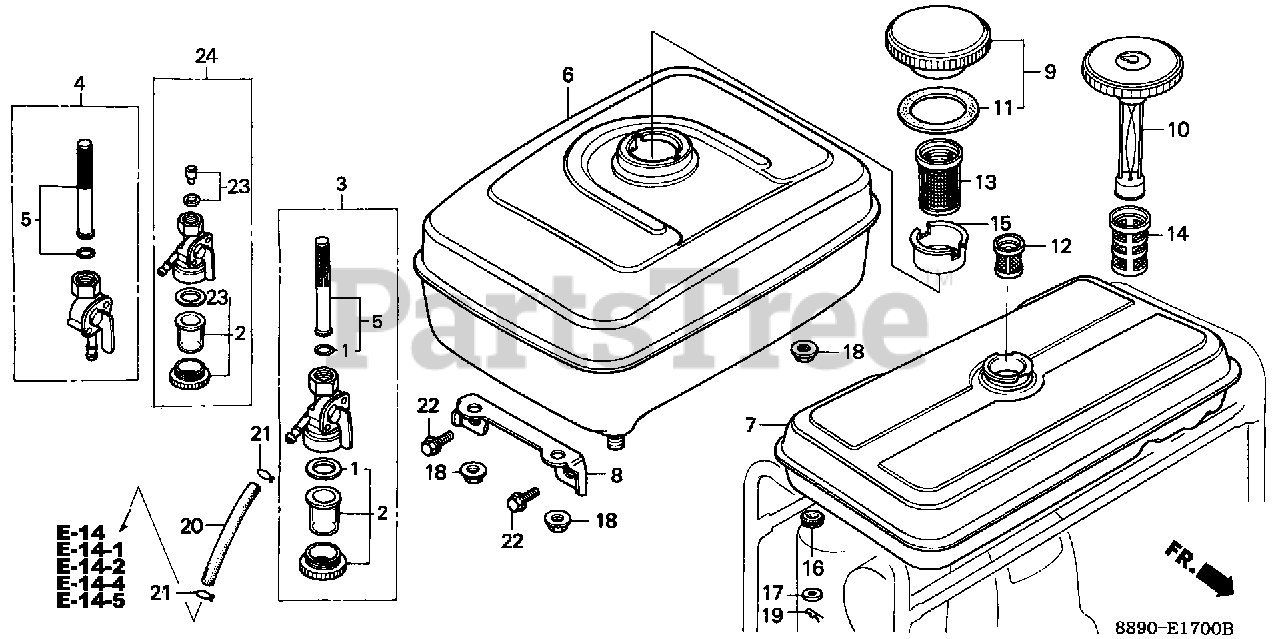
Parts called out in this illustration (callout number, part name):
1	GASKET SET, PETCOCK
2	CUP, FUEL STRAINER
2	CUP SET, FUEL STRAINER
3	PETCOCK ASSY.
4	PETCOCK ASSY.
4	PETCOCK ASSY. (NOT AVAILABLE)
5	SCREEN SET
6	TANK, FUEL *NH31* (MCKINLEY WHITE)
6	TANK, FUEL (LONG TAIL) (NOT AVAILABLE)
6	TANK, FUEL *NH31* (MCKINLEY WHITE) (NOT AVAILABLE)
8	STAY, FUEL TANK (NOT AVAILABLE)
9	CAP, FUEL FILLER (BLACK)
9	CAP, FUEL FILLER
10	GAUGE, FUEL (ENGLISH)
11	GASKET, FUEL FILLER CAP (39X58X3)
13	FILTER, FUEL
15	HOLDER, FUEL FILTER
18	NUT, FLANGE (8MM)
20	BULK HOSE, FUEL (4.5X3000) (4.5X85)
21	CLIP, TUBE (B8)
22	BOLT, FLANGE (8X16)
23	GASKET SET, PETCOCK (NOT AVAILABLE)
24	PETCOCK ASSY.
